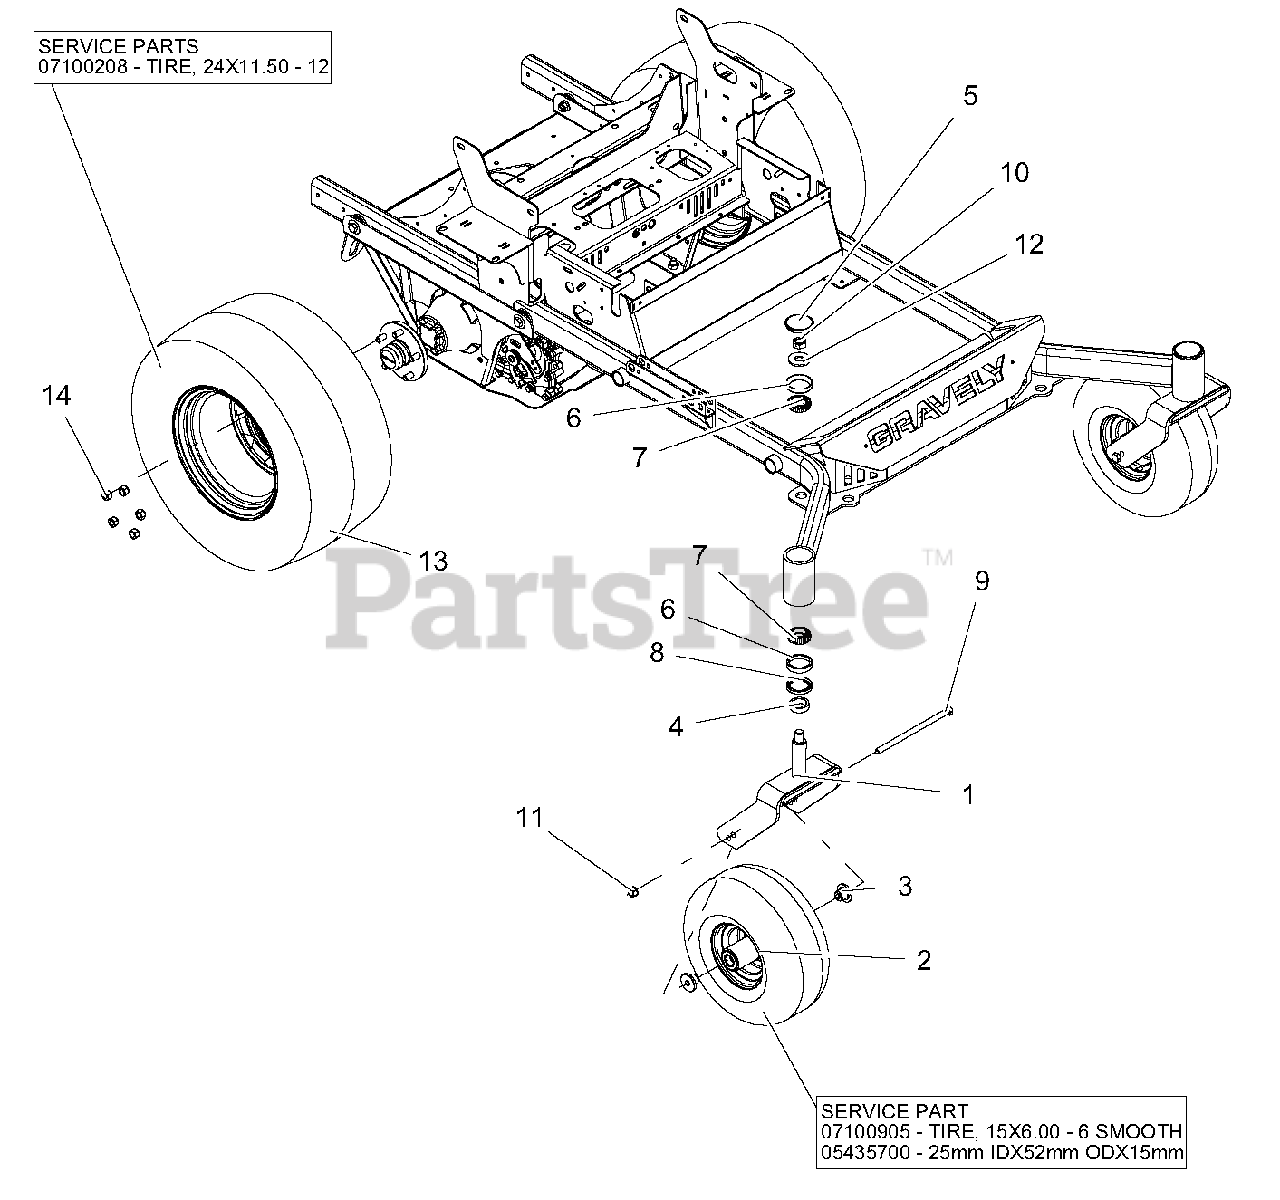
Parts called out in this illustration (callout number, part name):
1	WMT, CASTER FORK
2	TIRE/WHEEL, ASM 15X6.00-6 SMOOTH
3	SPACER, FRONT WHEEL
4	SPACER-1.258 ID X 1.750 OD X .550
5	CAP, DUST
6	BRG, CUP 2.328X.465
7	BRG, CONE 1.25 X .66
8	SEAL, OIL 1.75 X 2.332 X .312
9	BLT-HEX .50-13X9.00 GR5 YWZC
10	@NUT-LK-CTR-JAM .75-16 YWZC
11	@NUT, LK-TOP-FLG .50-13 YWZC
12	@WSHR-FL-STL.812X2.00X.148YWZC
13	TIRE/WHEEL ASSY, 24X11.50-12
14	NUT, LUG .500-13
